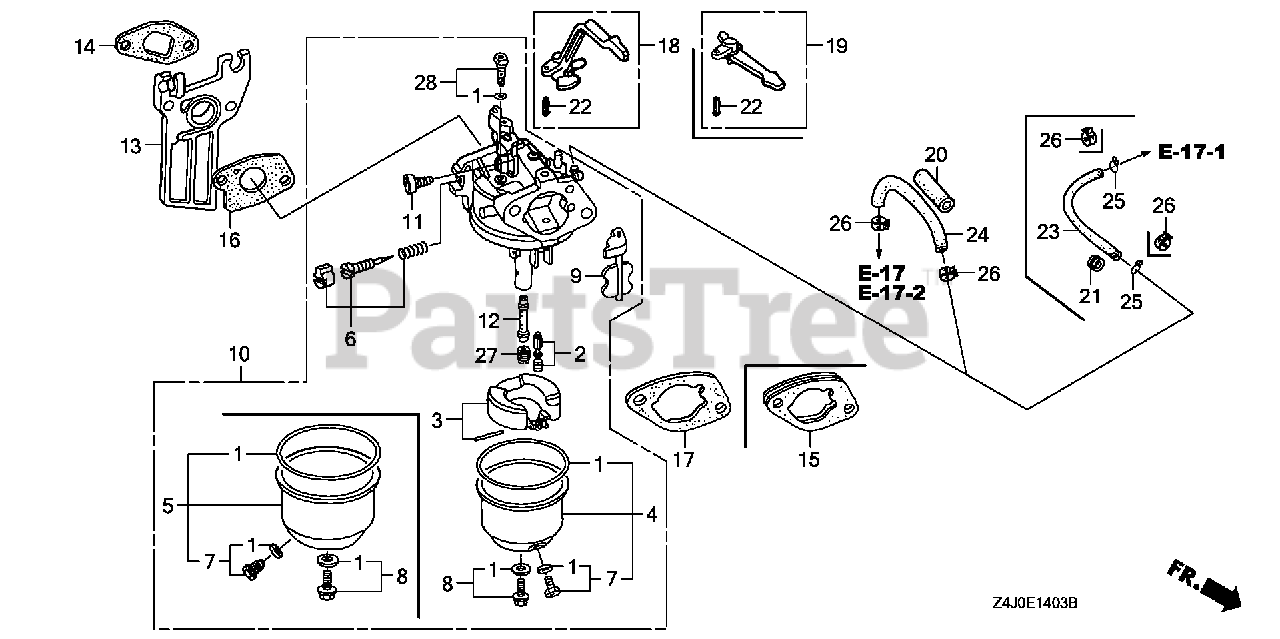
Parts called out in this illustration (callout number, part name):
1	GASKET SET
2	VALVE SET, FLOAT (SEAT NOT INCLUDED)
4	CHAMBER SET, FLOAT
6	SCREW SET, PILOT
7	SCREW SET, DRAIN
8	SCREW SET
10	CARBURETOR ASSY. (BE67P A)
11	SCREW, THROTTLE STOP
12	NOZZLE, MAIN
13	INSULATOR, CARBURETOR
14	GASKET, INSULATOR
16	GASKET, CARBURETOR
17	GASKET, AIR CLEANER
18	LEVER, CHOKE
22	PIN, SPRING (2X12)
27	JET, MAIN (#72)
27	JET, MAIN (#75)
27	JET, MAIN (#70)
28	JET SET, PILOT (#35)
